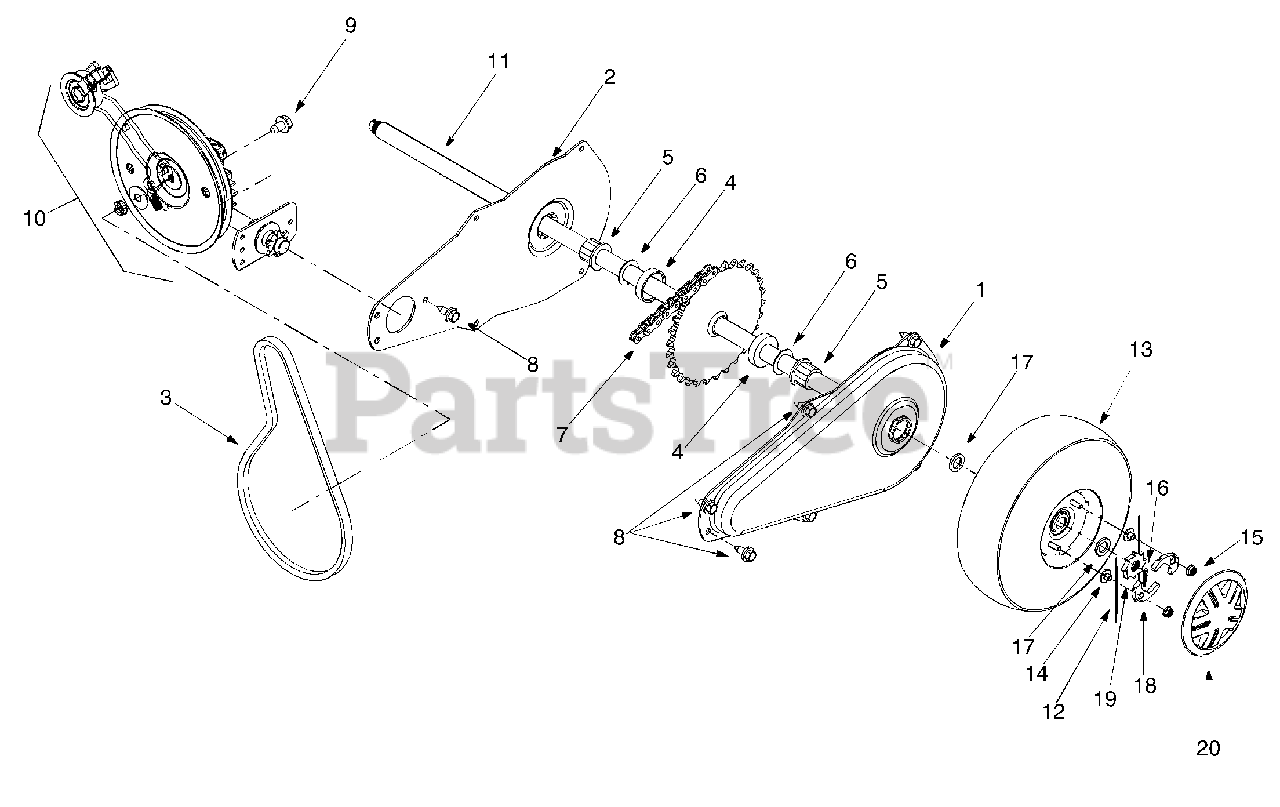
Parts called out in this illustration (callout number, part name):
3	V-Belt
5	Hex Flange Bearing
6	Flat Washer
7	Chain
8	Hex Washer Screw 1/4-14
9	Hex Washer Screw 5/16
10	Transmission Asm
12	Plastic Spring Ratchet
14	Hex Nut 1/4-20
15	Hex Flanged Lock Nut 1/4-20
16	Cotter Pin
17	Flat Washer 5/8 ID x 1.0 OD
18	Pawl LH .345 ID
19	Wheel Ratchet 1.62 OD x .5 serr
20	Hubcap
